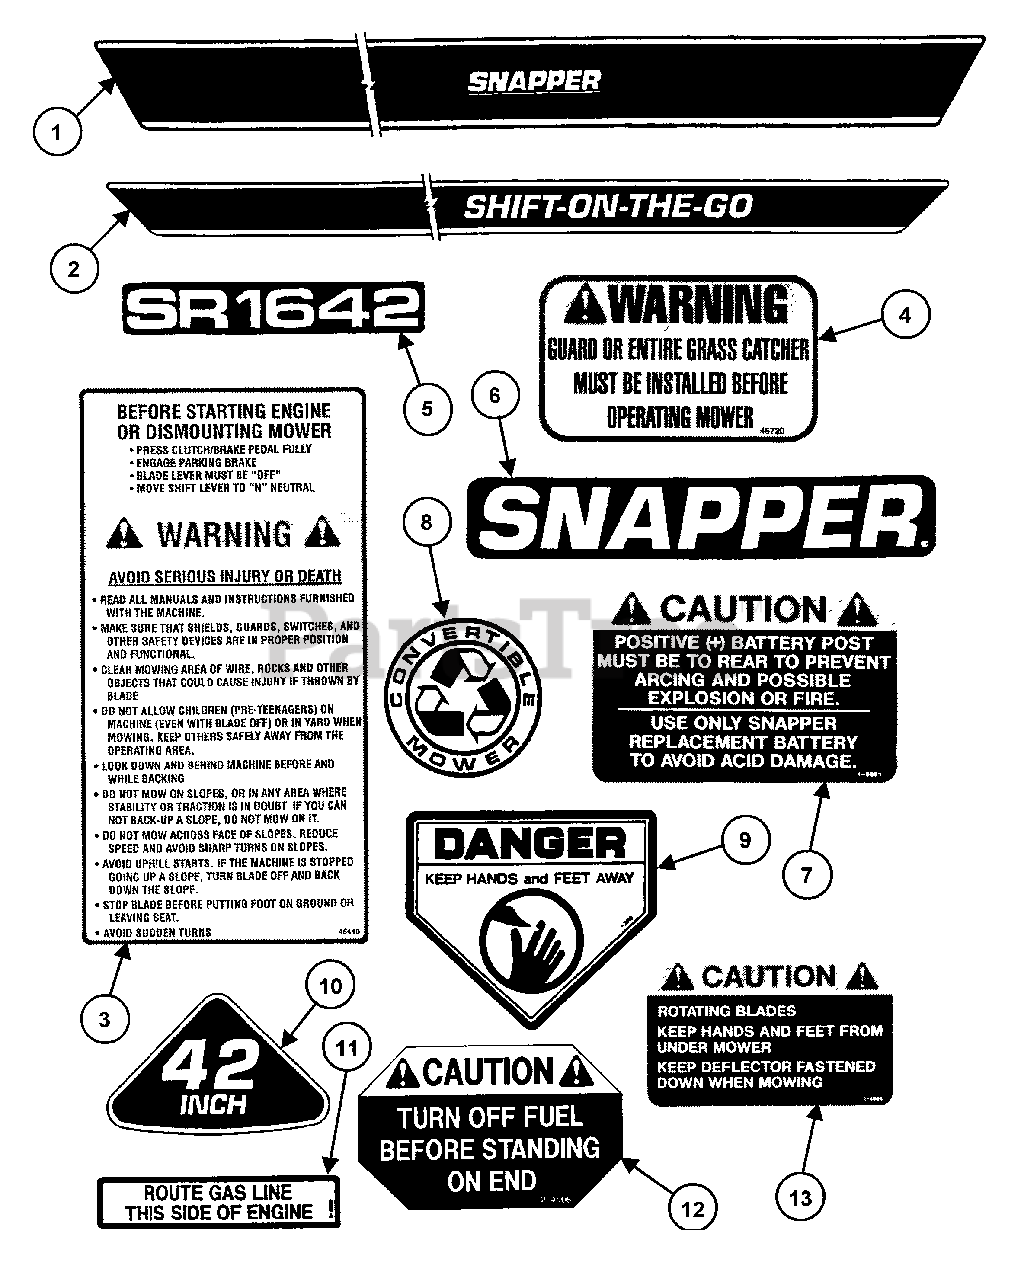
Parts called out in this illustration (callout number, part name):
1	DECAL, Banner (Blue)
2	DECAL, Bumper Stripe (Blue)
3	DECAL, Warning, Safety Instruction
4	DECAL, Chute/Deflector
5	DECAL, SR1642
6	LOGO, SNAPPER (Molded Logo)
7	DECAL, Caution, Battery
8	LOGO, Convertible (Blue)
9	DECAL, Danger (Heavy Adhesive)
10	DECAL, 42 Inch
11	DECAL, Fuel Routing
12	DECAL, Fuel Shut-Off
13	DECAL. Caution
